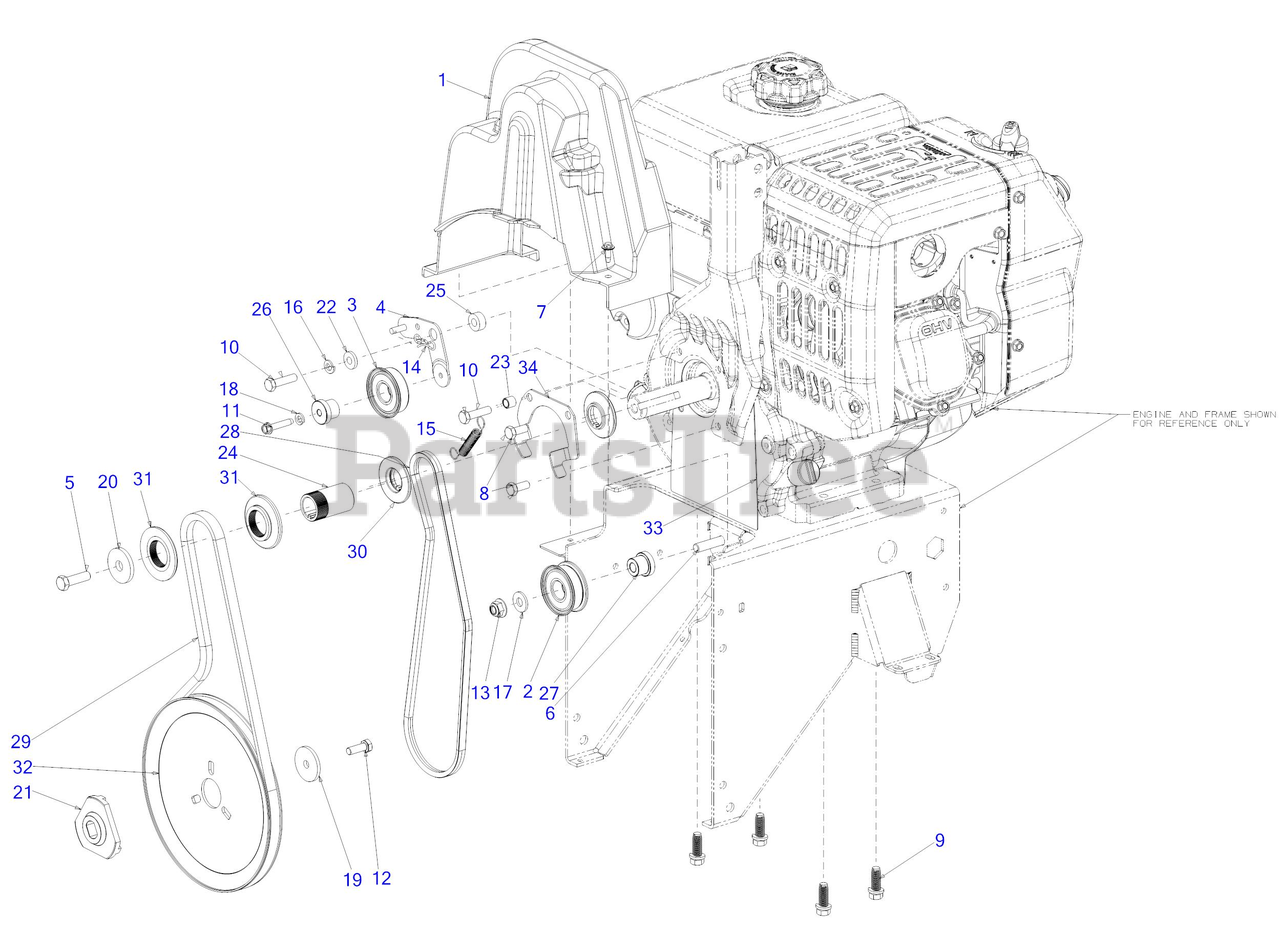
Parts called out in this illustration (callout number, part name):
1	BELT COVER ASSEMBLY
2	IDLER PULLEY ASSEMBLY
3	IDLER PULLEY ASSEMBLY
4	HYDRO DRIVE IDLER ASSEMBLY
5	SCREW 3/8-24X1.25
6	SCREW 3/8-16 x 1.50
7	SCREW M6-1 x .625
8	SCREW 5/16-24 x .750 GR5
9	SCREW 3/8-16 x 1
10	SCREW 5/16-24 x 1.25 GR5
11	SCREW 1/4-20 x 1.25
12	SCREW 5/16-24 x .875 GR5
14	BOW TIE COTTER PIN 1/4-5/16
15	EXTENSION SPRING 2.675
16	LOCK WASHER 5/16
17	FLAT WASHER .385X.870X.090
18	LOCK WASHER
19	FLAT WASHER
20	FLAT WASHER .45 x 1.5 x .172 HT
21	ADAPTER PULLEY .75 DIA W/DD
22	SHOULDER SPACER
24	PULLEY SPACER
25	IDLER BRACKET SPACER .340X.750X.330
26	SHOULDER SPACER
27	SHOULDER SPACER .385 x .785 x .538
28	HYDRO DRIVE BELT
29	AUGER BELT .500 X 41.40
30	HALF PULLEY-3/8 V x 1.7160
31	HALF PULLEY 4L-V x 2.40 OD
32	AUGER PULLEY 8.5 OD
33	ENGINE PLATE (FRONT COVER)
34	BELT KEEPER BRACKET
